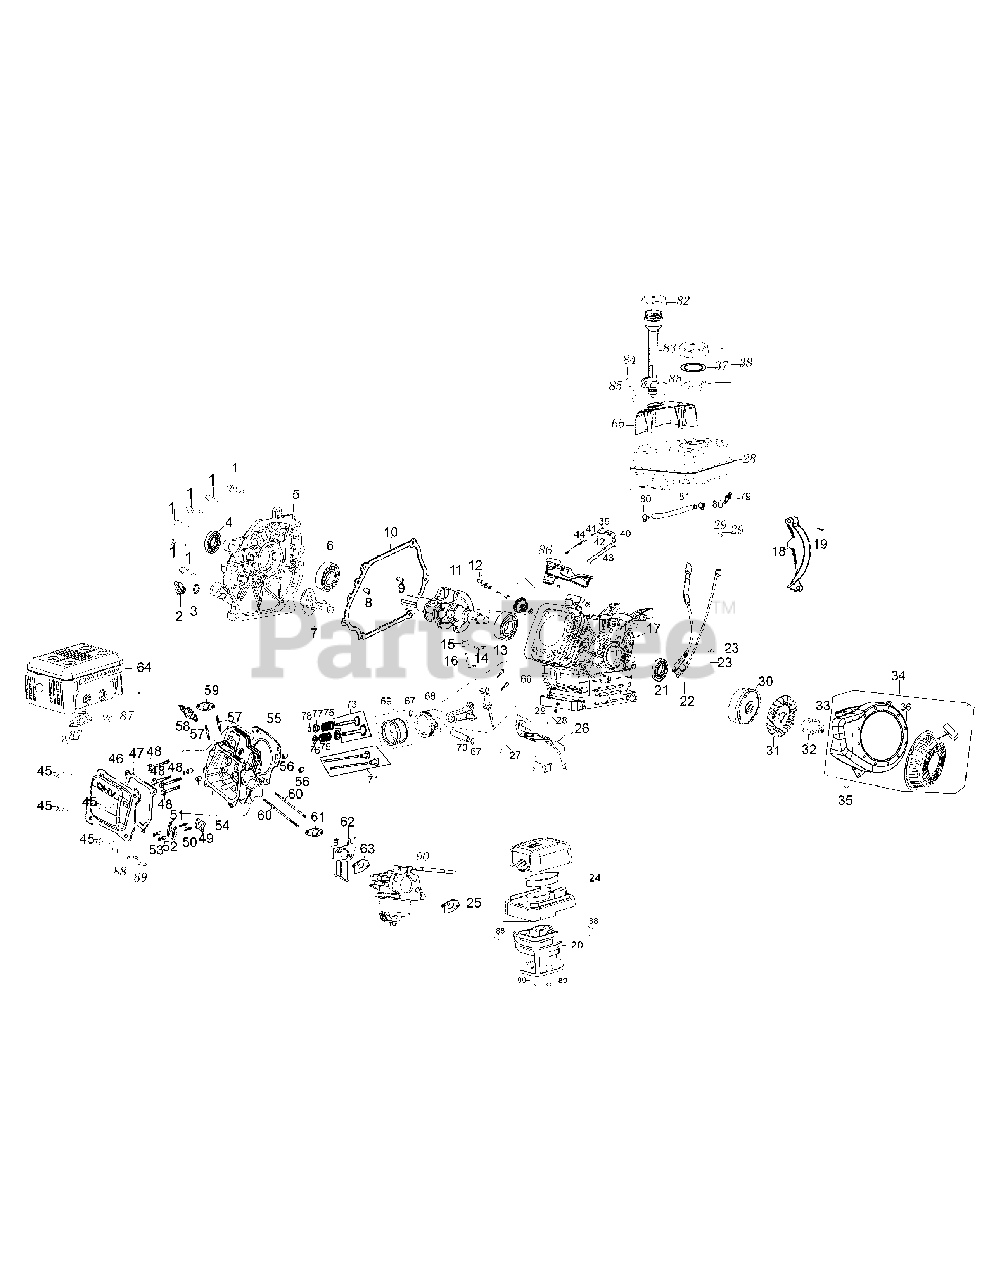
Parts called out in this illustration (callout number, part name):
1	Bolt
2	Oil Filler Plug
3	O-Ring
4	Oil Seal
5	Left Crankcase Cover
6	Radial Ball Bearing
7	Camshaft Assembly
8	Dowel Pin
9	Dowel Pin
10	Case Cover Packing
11	Crankshaft Complete
12	Governor Kit
13	Radial Ball Bearing
14	Lock Pin
15	O-Ring
16	Governor Arm
17	Crankase Complete
20	Air Filter Heating Pipe Base
21	Oil Seal
22	Ignition Complete
24	Air Filter Housing
24	Air Filter
25	Carburetor Packing
28	Fuel Tank
28	Bolt
29	Nut
34	Recoil Starter Assembly
38	Fuel Filler Cap Complete
44	Governor Spring
47	Head Cover Gasket
51	Rocker Arm
52	Valve Adjusting Nut
53	Pivot Locking Nut
54	Cylinder Head Complete
55	Cylinder Head Gasket
56	Dowel Pin
57	Stud 8 × 34
58	Spark Plug
59	Muffler Gasket
61	Carburetor Insulator Packing
62	Carburetor Insulator
64	Muffler
65	Dipstick Decoration Cover
66	Connecting Rod Assembly
67	Piston Pin Clip
68	Piston
69	Piston First Ring Set
70	Piston Pin
71	Push Rod Kit
71	Valve Lifter
71	Push Rod
73	Inlet Valve
73	Exhaust Valve
79	Fuel Tank Nipple
82	Dipstick
83	Engine/Dipstick Cover
85	Bolt - M6 X 28 Zinc Coating
90	Carburetor
